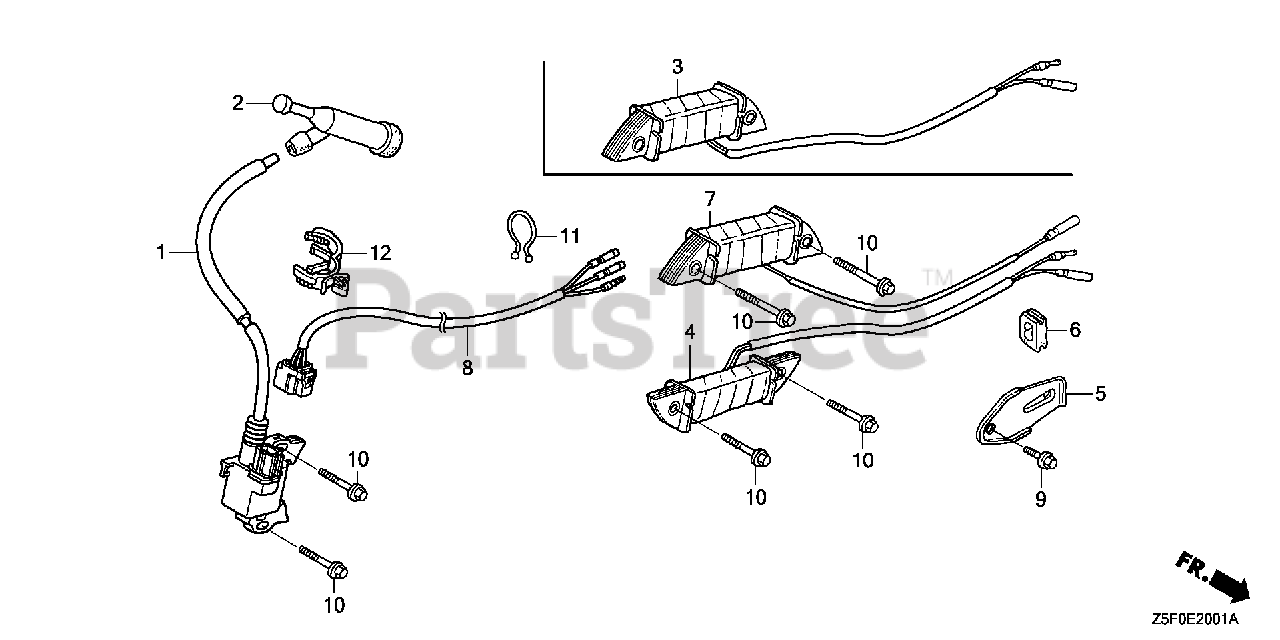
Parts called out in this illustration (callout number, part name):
1	COIL ASSY., IGNITION
2	CAP ASSY., NOISE SUPPRESSOR (NICHIWA Y-EZ RTFM256)
6	GROMMET, WIRE
8	WIRE HARNESS ASSY., ENGINE
10	BOLT, FLANGE (6X28) (CT200)
12	CLIP, HARNESS
